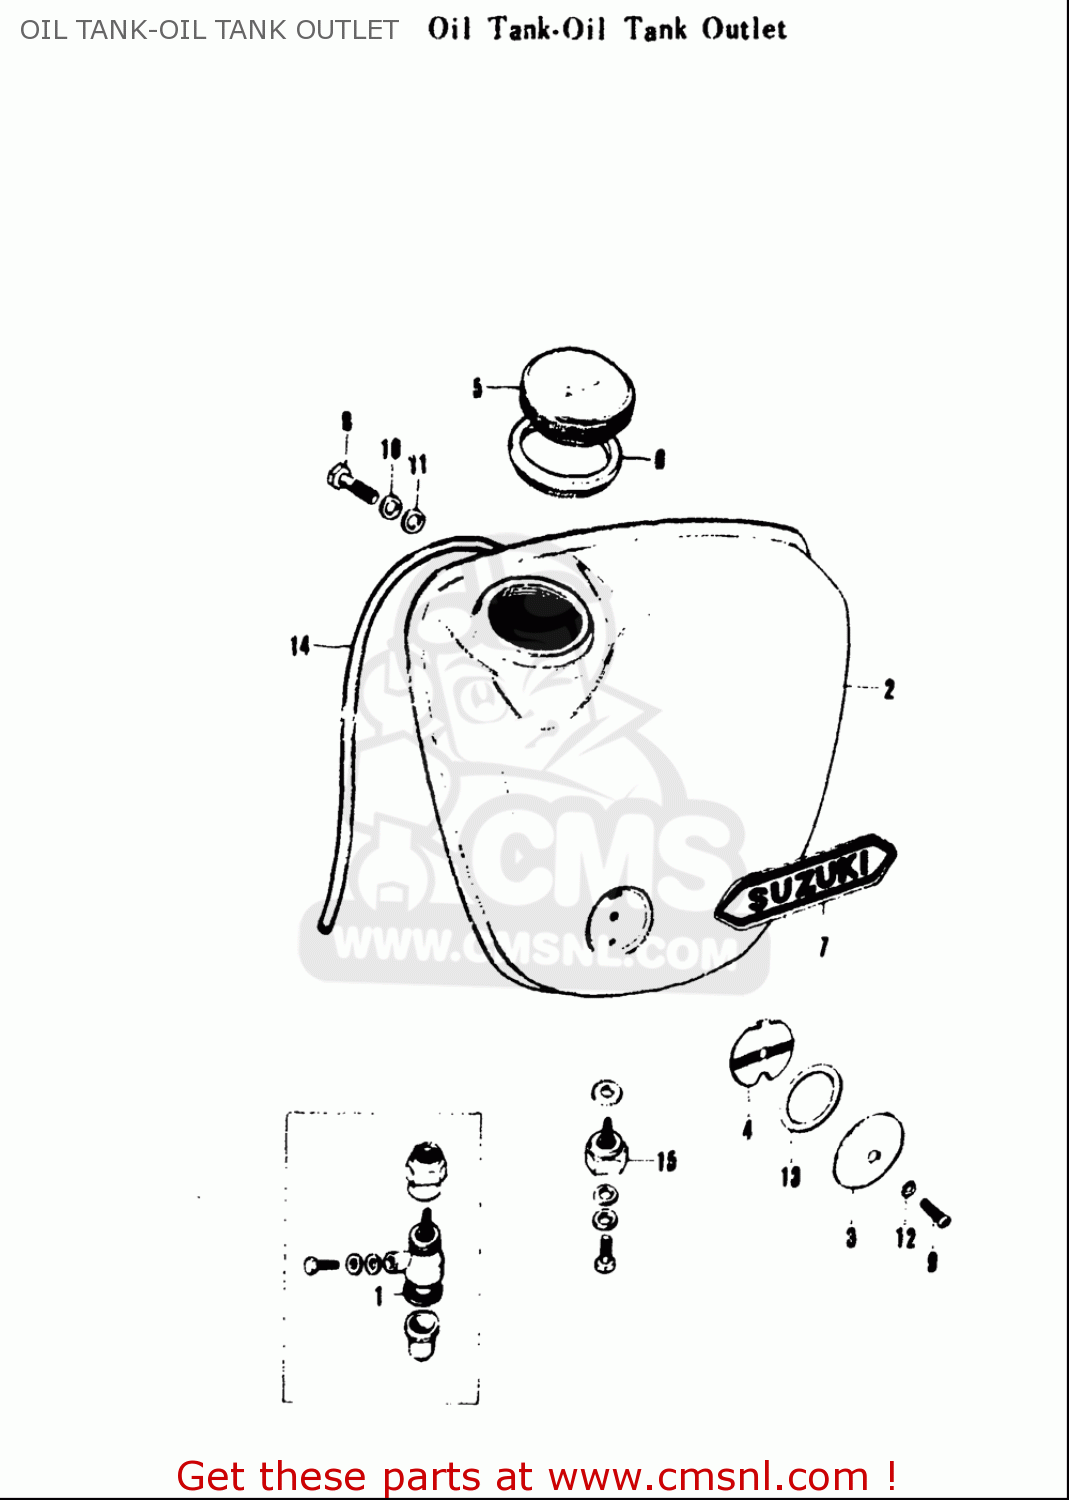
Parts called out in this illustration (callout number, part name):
4	LENS SET,OIL INSPECTION
5	CAP,OIL TANK
6	GASKET,OIL TANK FILLER CAP (NAS)
9	SCREW
10	WASHER,LOCK
11	WASHER
12	GASKET(5X9.5X1) (NAS)
13	O RING(D:3,ID:23)
14	HOSE(5X8X2000)
